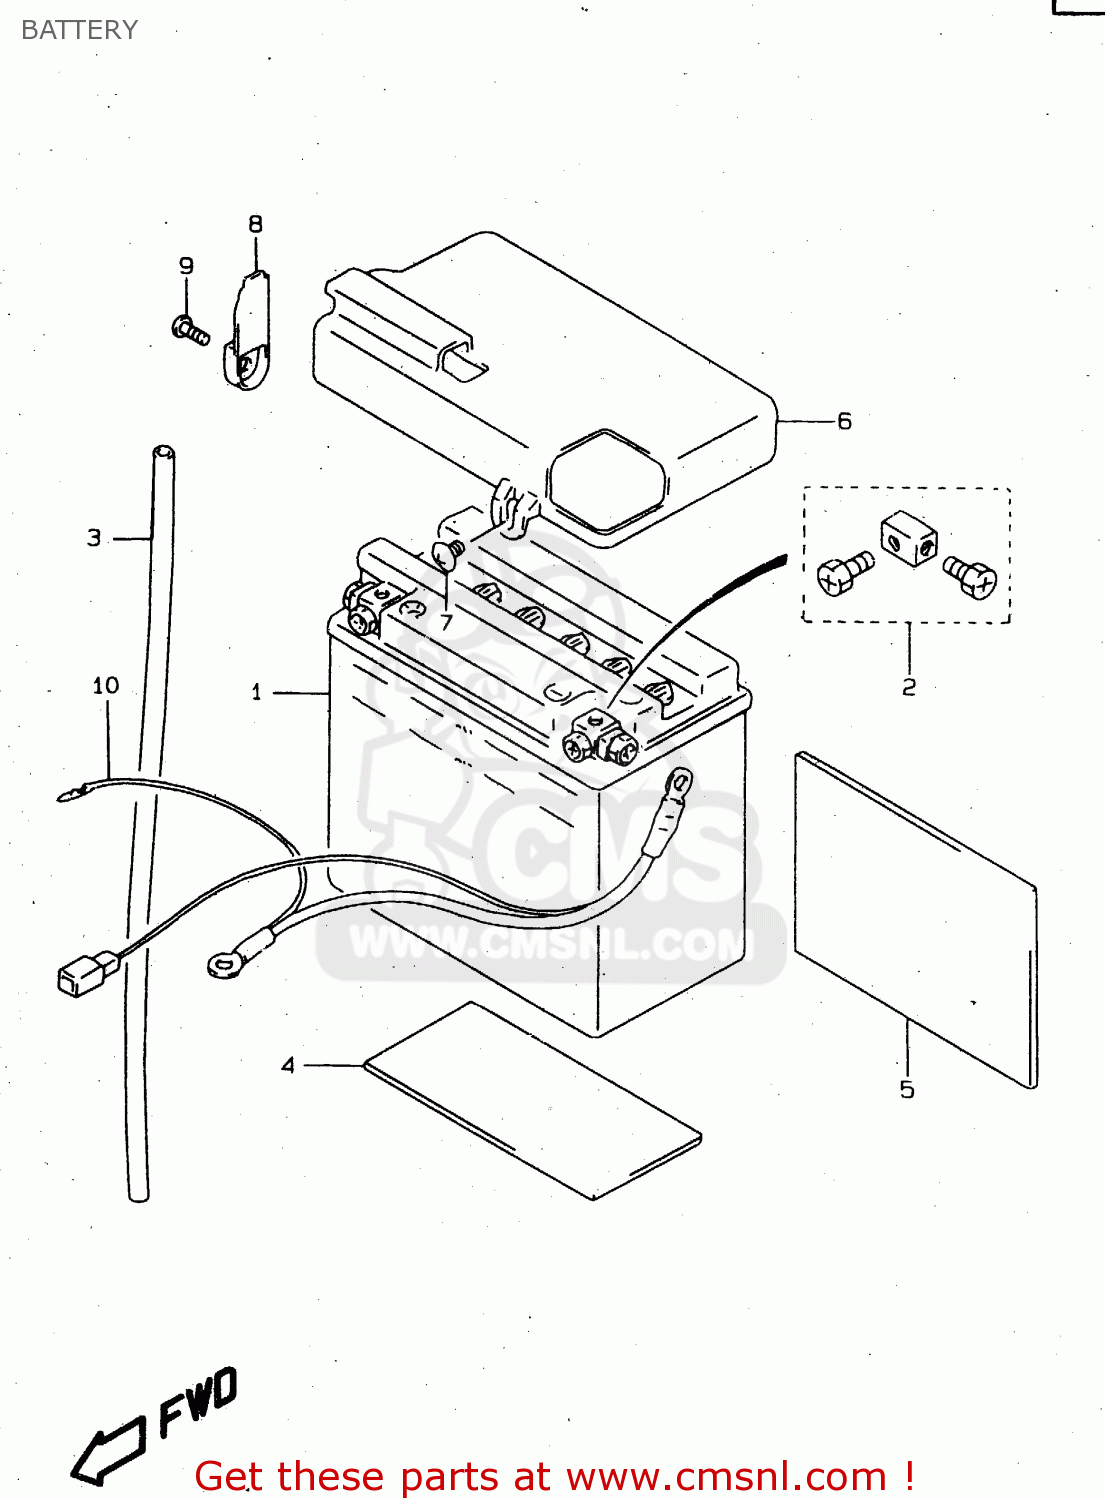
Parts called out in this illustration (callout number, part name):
1	BATTERY ASSY (12V)
2	BOLT SET,BATTERY TERMINAL
3	HOSE,BATTERY EXHAUST(L:780)
4	PROTECTOR(170X95X3.0)
5	PROTECTOR(80X80X2)
6	COVER,BATTERY UPR
7	SCREW
8	COVER,BATTERY TERMINAL
9	SCREW
10	WIRE,BATTERY MINUS LEAD
